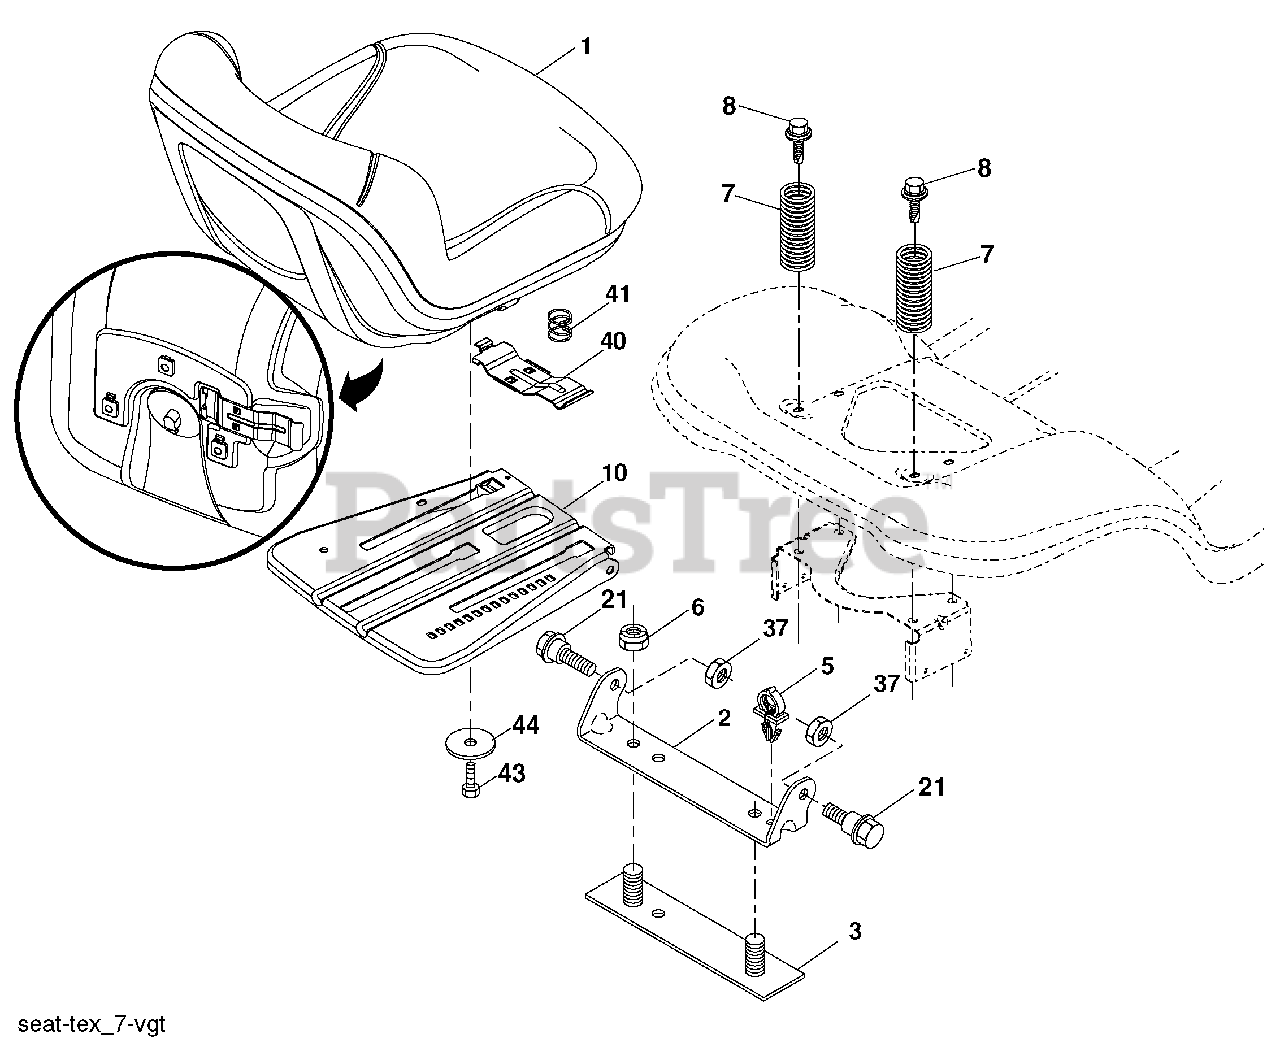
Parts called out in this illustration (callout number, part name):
1	Seat
2	Bracket Pivot Fender
3	Strap, Asm Fender
5	Clip, Push In, Hinged
6	Nut, Lock W/Ins. 3/8-16 unc
7	Spring, Seat Cprsn
8	Bolt 5/16-18 uncx 3/4 w/Sems
10	Pan, Seat
21	Bolt, Shoulder 5/16-18
37	Nut, Lock 5/16-18 unc
40	Handle Slide Seat
41	Spring Latch Seat
43	Bolt Fin Hex 3/8-16 UNC x 3/4
44	Washer 13/32 x 2-3/8 x 12Ga.
